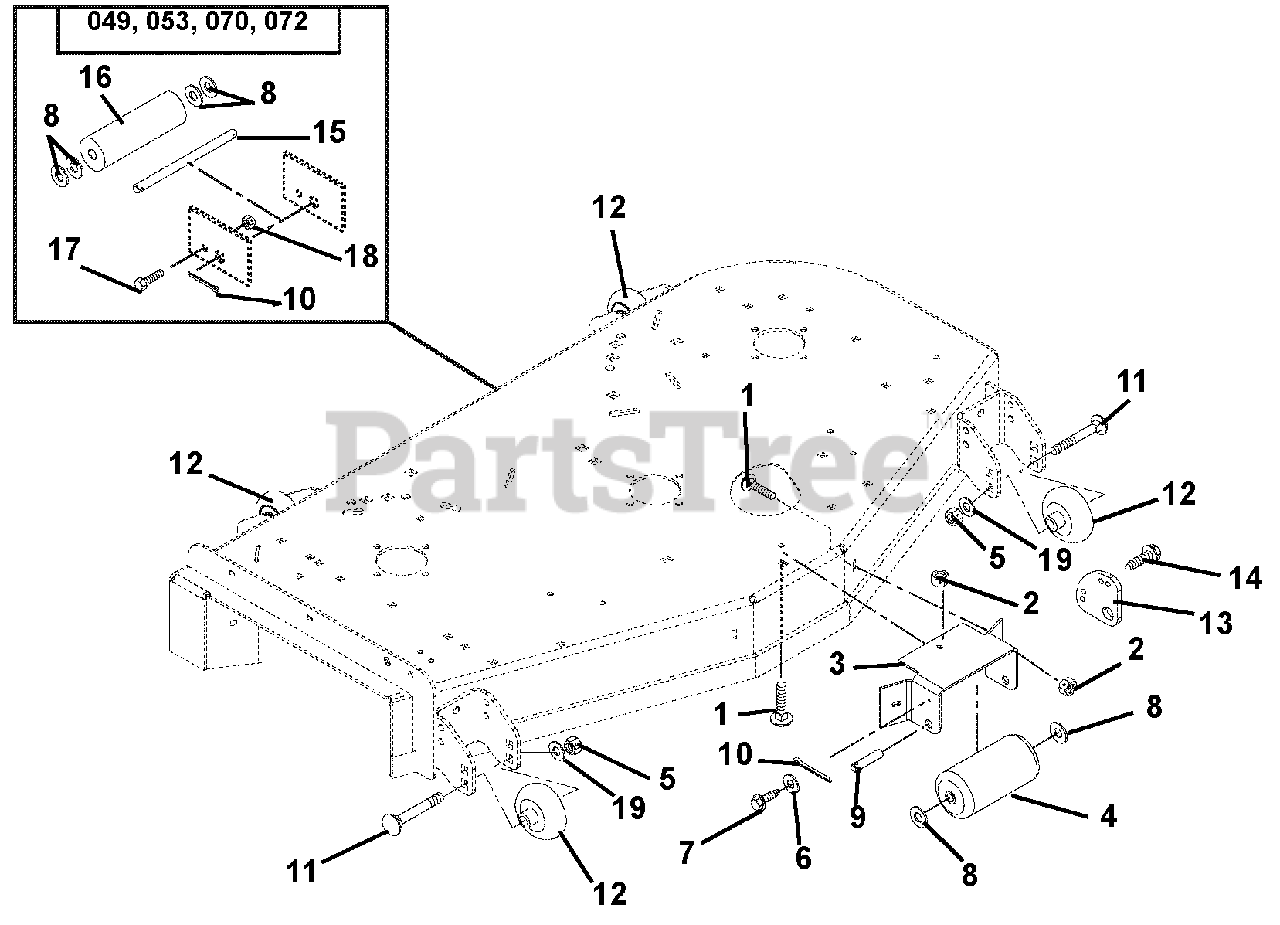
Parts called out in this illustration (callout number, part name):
1	Bolt-Round Head Square Neck .38-16 x 1.00 Grade 5
2	Nut-Locking-Top-Flange .38-16
3	Bracket- Anti-Scalp Roller
5	Nut-Locking-Nylon .50-13
6	Washer-Flat-Steel .281 x .62 x .065
7	Screw-Tapping .25-20 x .75 Hex Washer Head
8	Washer-Flat-Steel .656 x 1.31 x .095 (045, 046, 047, 052, 066, 067, 068, 071, 084, 085, 087, 088, 089,
10	Pin-Cotter .25 x 2.00 (045, 046, 047, 052, 066, 067, 068, 071, 084, 085, 087, 088, 089, 102, 103, 104,
11	Bolt-Round Head Square Neck .50-13 x 5.00 Grade 2
12	Wheel, 3 x 5
13	Anti-Scalp Washer
14	Screw-Tapping .25-20 x .62 Hex Washer Head
15	Shift, Center Roller (086, 091, 107)
16	Roller, Gage (086, 091, 107)
17	Bolt-Hex .25-20 x .75 Grade 5 (086, 091, 107)
18	Nut-Locking-Center .25-20 (086, 091, 107)
19	Washer-Flat-Steel .531 x 1.06 x .095
